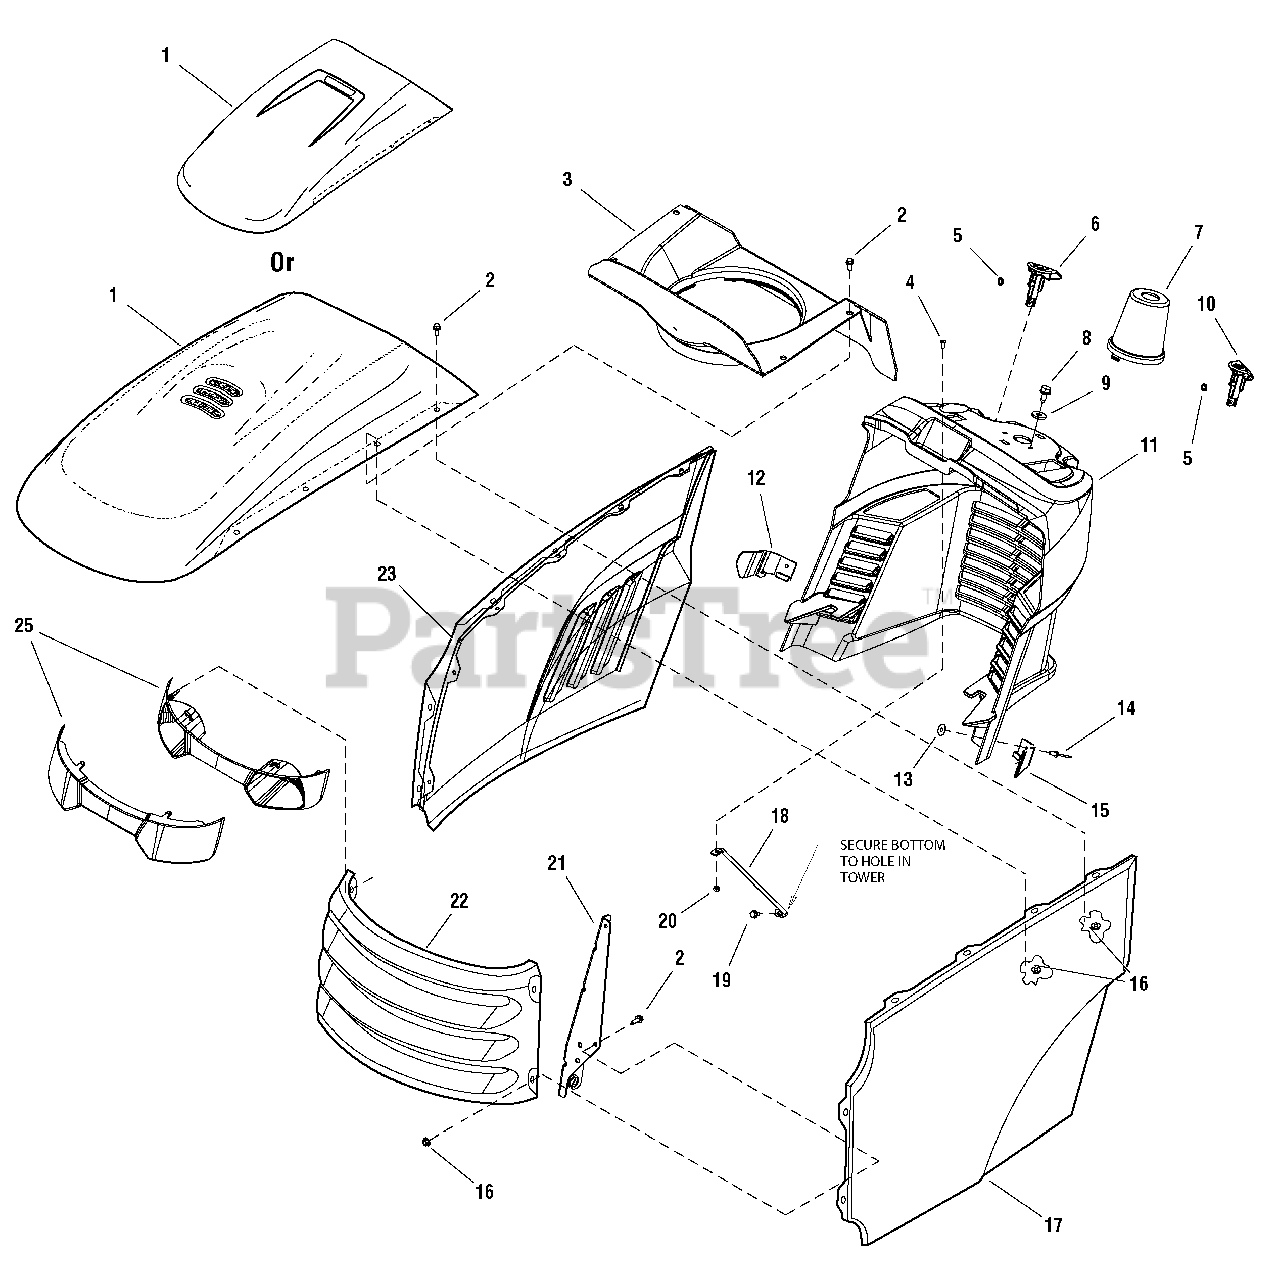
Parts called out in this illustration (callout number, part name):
1	HOOD, with Scoop
1	HOOD, with Louver
2	CAPSCREW, Whizlock, 1/4-20 x 5/8
3	DUCT, Air Inlet Plastic
4	SCREW, Phillips Head
5	NUT, Push Pal
6	KNOB, Cruise Lock Green Plastic
7	COVER, Steering Shaft Plastic
8	CAPSCREW, Hex Head, Taptite, 5/16-18 x 3/4
9	WASHER, Plain, 5/16
10	KNOB, Brake Lock Plastic
11	DASHBOARD
12	GUIDE, Hood R.H.
13	WASHER, 1/8 x 3/4
14	RIVET, Pop, Stem Black
15	GUIDE, Hood L.H.
16	NUT, Hex Flange Whiz, 1/4-20
17	PANEL, Hood, L.H.
18	ROD, Dash Support
19	SCREW, Self-Tap
20	NUT, Hex, Nylon, Lock, #10-24
21	HINGE, Hood R.H.
21	HINGE, Hood L.H.
22	GRILLE
23	PANEL, Hood R.H.
24	INSERT, Lightbar
25	HEADLIGHT ASSEMBLY
